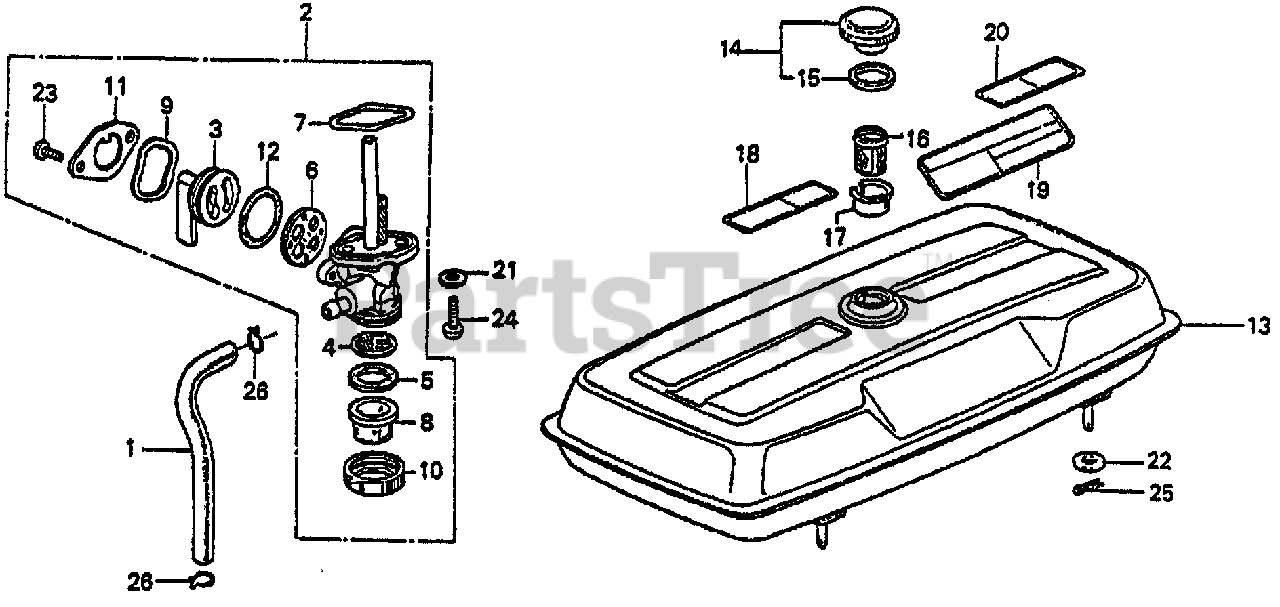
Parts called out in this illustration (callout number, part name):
1	TUBE, CARBURETOR FUEL (NOT AVAILABLE)
2	PETCOCK ASSY.
3	LEVER, VALVE
4	GASKET SET, VALVE
5	GASKET, FUEL STRAINER CUP
6	GASKET, VALVE
7	RING, PETCOCK SEAL
8	BOWL, FUEL
9	SPRING, LEVER (NOT AVAILABLE)
10	NUT, RING (NOT AVAILABLE)
11	STOPPER, LEVER (NOT AVAILABLE)
12	O-RING (21MM) (NOT AVAILABLE)
13	TANK, FUEL *NH31* (MCKINLEY WHITE) (NOT AVAILABLE)
14	CAP, FUEL FILLER
15	GASKET, FUEL FILLER CAP
16	FILTER, FUEL
17	HOLDER, FUEL FILTER
18	MARK A, CAUTION
19	PLATE, CAUTION
20	MARK, CAUTION (ENGLISH/FRENCH/SPANISH)
21	GASKET, FIBER (6MM)
22	WASHER, FLAT (20MM)
23	SCREW, PAN (3X8)
24	SCREW, PAN (6X16)
25	PIN, LOCK (8MM)
26	CLIP, TUBE (B12)
